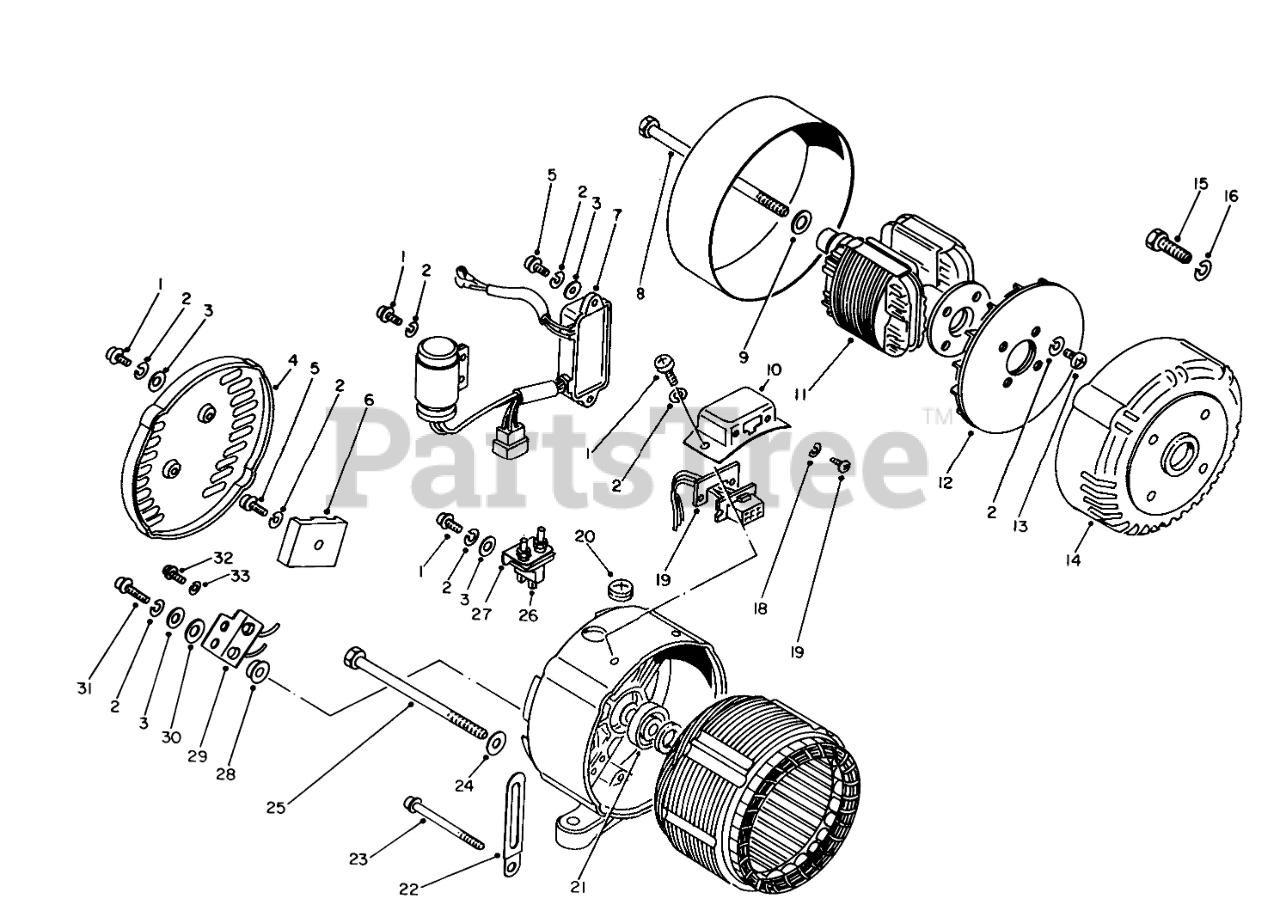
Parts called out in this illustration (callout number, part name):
1	SCREW
2	Washer
3	WASHER
4	Cover-Rear
5	Screw
6	Terminal
7	REGULATOR
9	Washer
10	COUPLER COVER
11	Rotor
13	Screw
14	Generator (Incl. Ref. #2, 8-9 & 11-13)
16	Lockwasher
17	SCREW
18	Lockwasher
19	Plate
20	GROMMET
21	Bearing
22	Clamp
23	Screw
24	Washer
26	BRUSH
27	Holder
28	Brush
29	DIODE
30	Washer
31	Screw
33	Lockwasher
